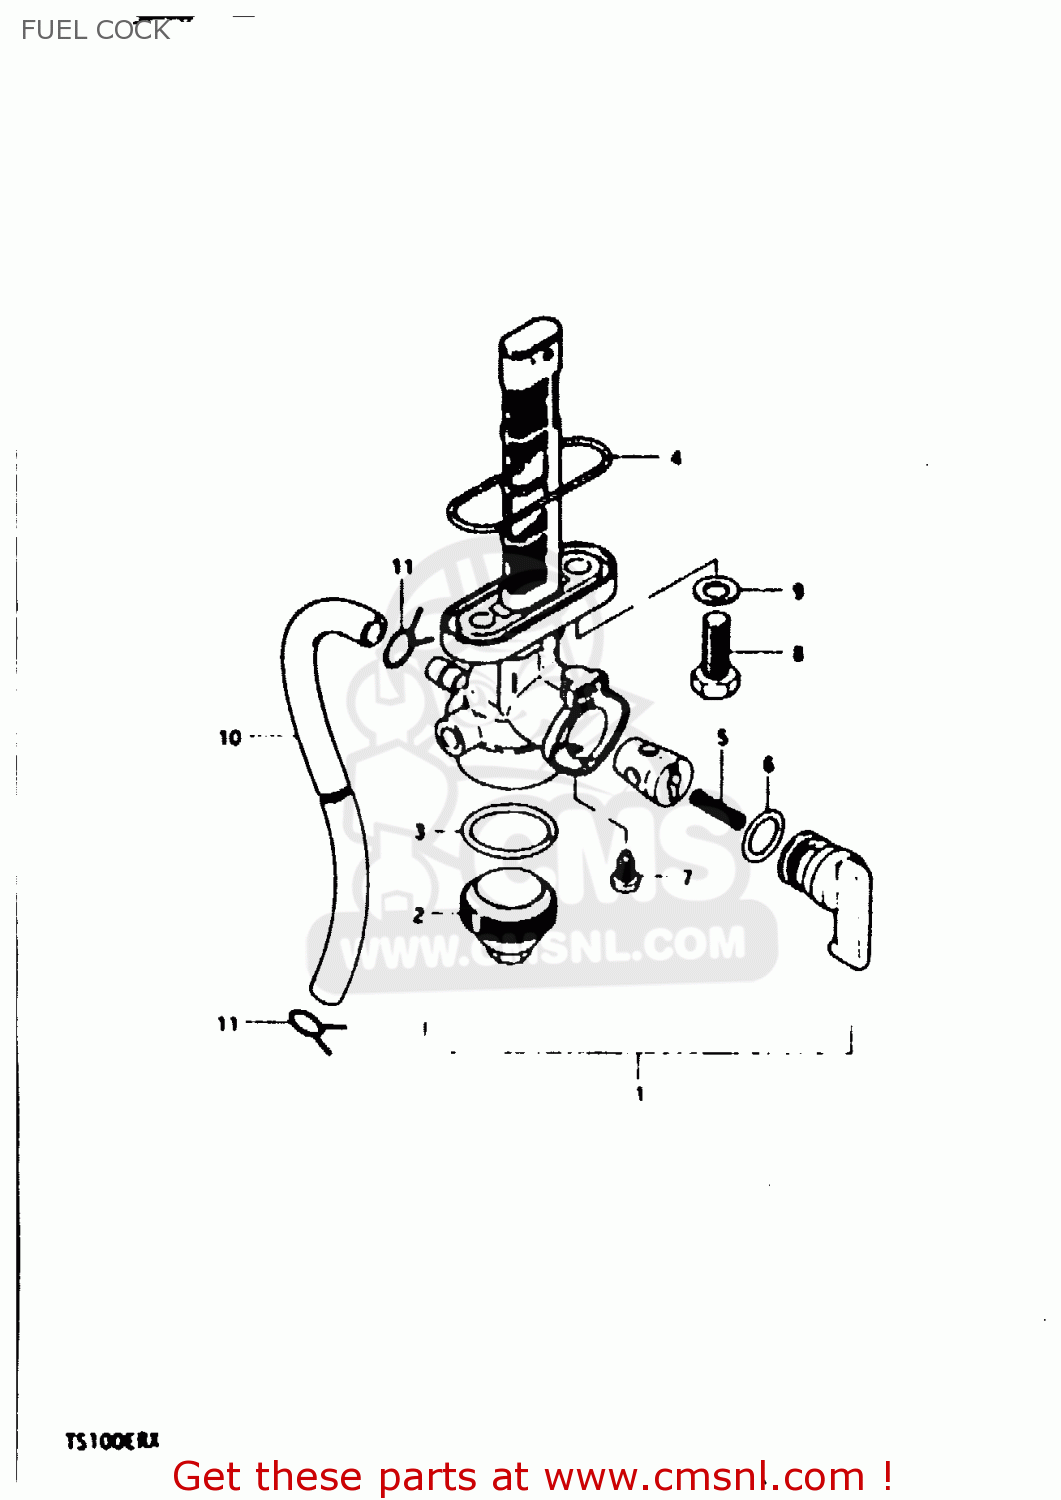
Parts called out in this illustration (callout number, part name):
1	COCK ASSEMBLY,FUEL
2	CUP,STRAINER
3	GASKET,FILTER (NAS)
4	O RING,FUEL COCK
5	SPRING
6	O-RING
7	SCREW
8	BOLT(6X20)
9	GASKET
10	HOSE
11	CLIP
